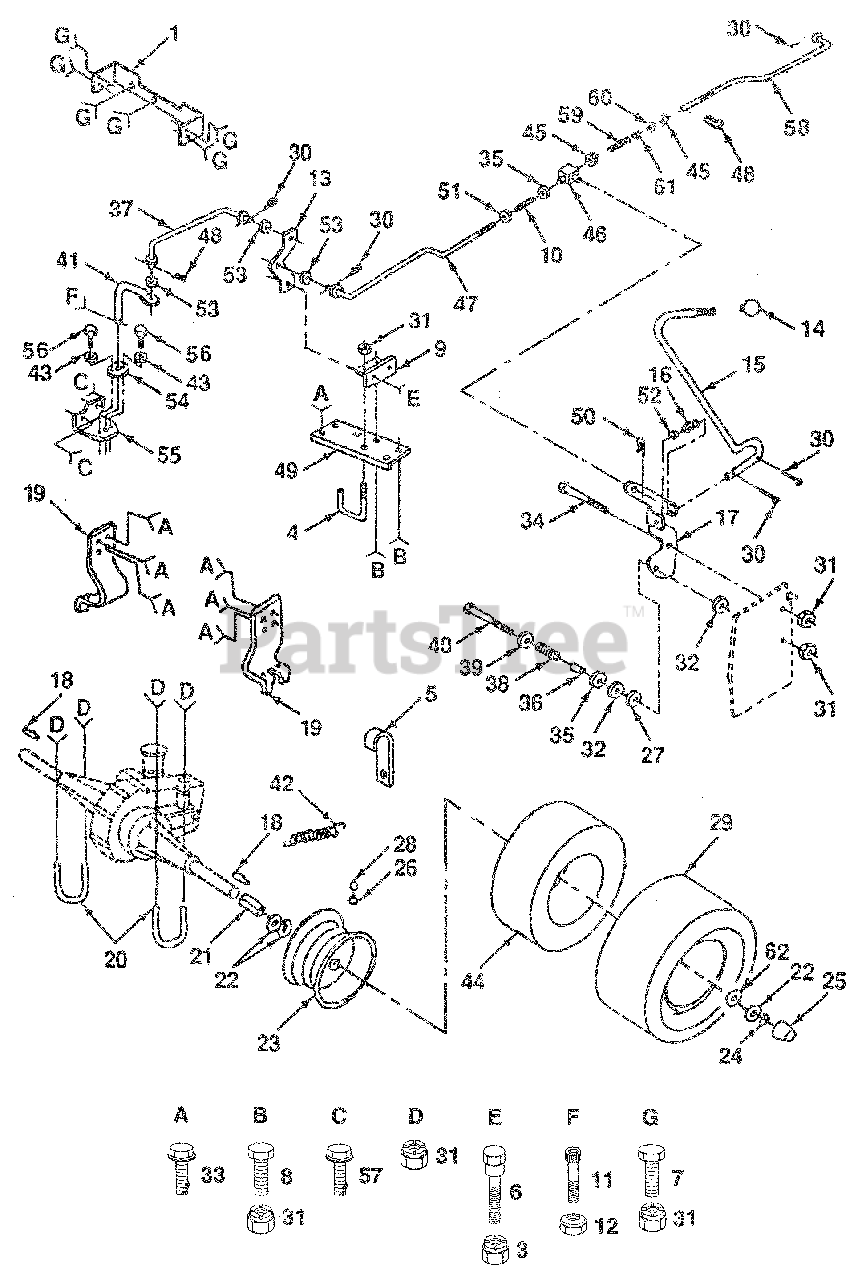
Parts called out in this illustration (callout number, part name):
1	Bracket, Mounting, Hydro Transaxle, Agri-Fab, Hydro, Model
2	Number 121431X
3	Nut, Crownlock 5/16-18
4	Keeper, Centerspan
5	Clip, Fuel Line
6	Bolt, Shoulder 5/16-18
7	Bolt, Hex Fin 3/8-16 UNC x 3/4
8	Bolt, Hex Fin 3/8-16 UNC x 1
9	Bracket, Bellcrank, Pivot
10	Spring, Compression
11	Screw, Hex Socket Head #10-24 UNC
12	lockout #10-24
13	Bellcrank
14	Knob, Control
15	Rod, Control
16	Spring, Torsion
17	Bracket, Control Rod
18	Key, Square 2.5 x .1845/. 1865
19	Bracket, Transaxle
20	U-Bolt 3/8-16 x 2-7/8
21	Spacer, Split
22	Washer 25/32 x 1-1/4 x 16 Gauge
24	E-Ring
25	Cap, Axle
26	Stem, Valve
27	Washer, Phenolic
28	Cap, Valve
29	Tire, Rear
30	Pin, Cotter 1/8 x 3/4
31	Nut, Crownlock 3/8-16
32	Spacer, Nylon 1-1/2 x .65 ID x .185 THK
33	Screw, Hex Washer Head, Thd., Roll, 3/8-16 x 3/4
34	Bolt, Shoulder 3/8-16 x 1-3/8
35	Washer 21/32 x 1-1/4 x 16 Gauge
36	Spacer 13/32 x 5/8 x 2-1/2
37	Link, Control
38	Spring, Compression
39	Washer 13/32 x 1-1/4 x 12 Gauge
40	Bolt, Hex 3/8-16 x 3
41	Arm Assembly, Pump Control
42	Spring, Brake Return
43	Washer 7/32 x 1/2 x 16 Gauge
44	Tube, Tire
45	Lockout, Hex w/Washer Insert 3/8-16 UNC
46	Trunnion
47	Rod, Control, Adjustable
48	Clip, Hairpin
49	Bracket, Chassis Reinforcement, Hydro
50	Spring, Retainer
51	Washer 13/32 x 3/4 x 12 Gauge
52	Washer 15/32 x 15/16 x 16 Gauge
53	Washer, Spring
54	Guide, Control
55	Bracket, Control Guide
56	Screw Tap Hex #10-24 x .625
57	Screw, Thdrol 5/16 -18 x 3/4
58	Rod, Brake
59	Spring, Brake Rod
60	Washer 13/32 x 13/16x16 Gauge
61	Nut, Hex, Jam 3/8-16 UNC
62	Washer 25/32 x 1 -5/8 x 16 Ga.
